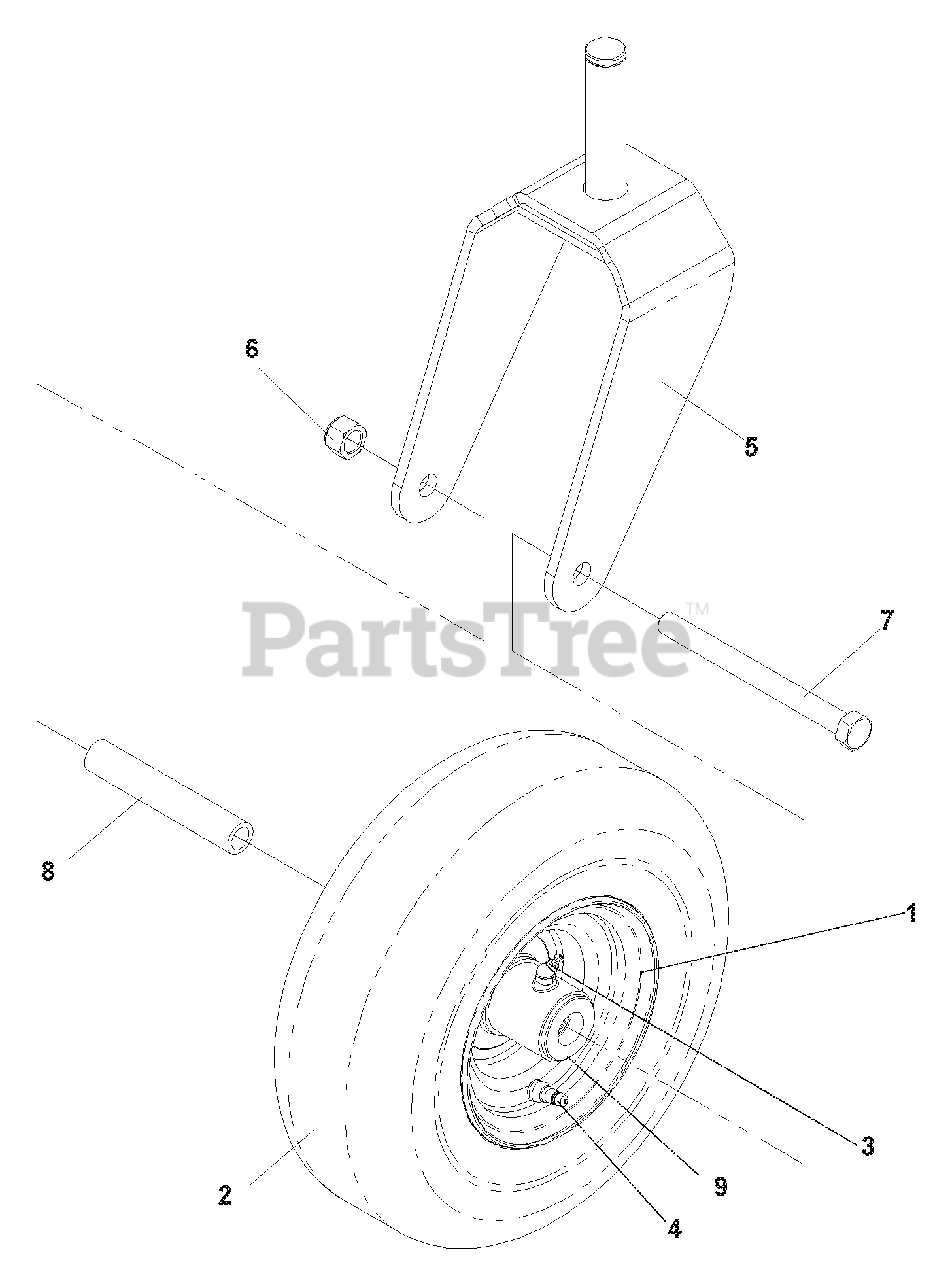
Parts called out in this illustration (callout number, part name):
2	TIRE 410/350-5, 4 PLY
3	ZERK
4	VALVE STEM
5	CASTER WELDMENT
6	NUT 1/2C, NYLOC
7	HCS 1/2C X 5 1/2
9	BEARING, FLANGE
